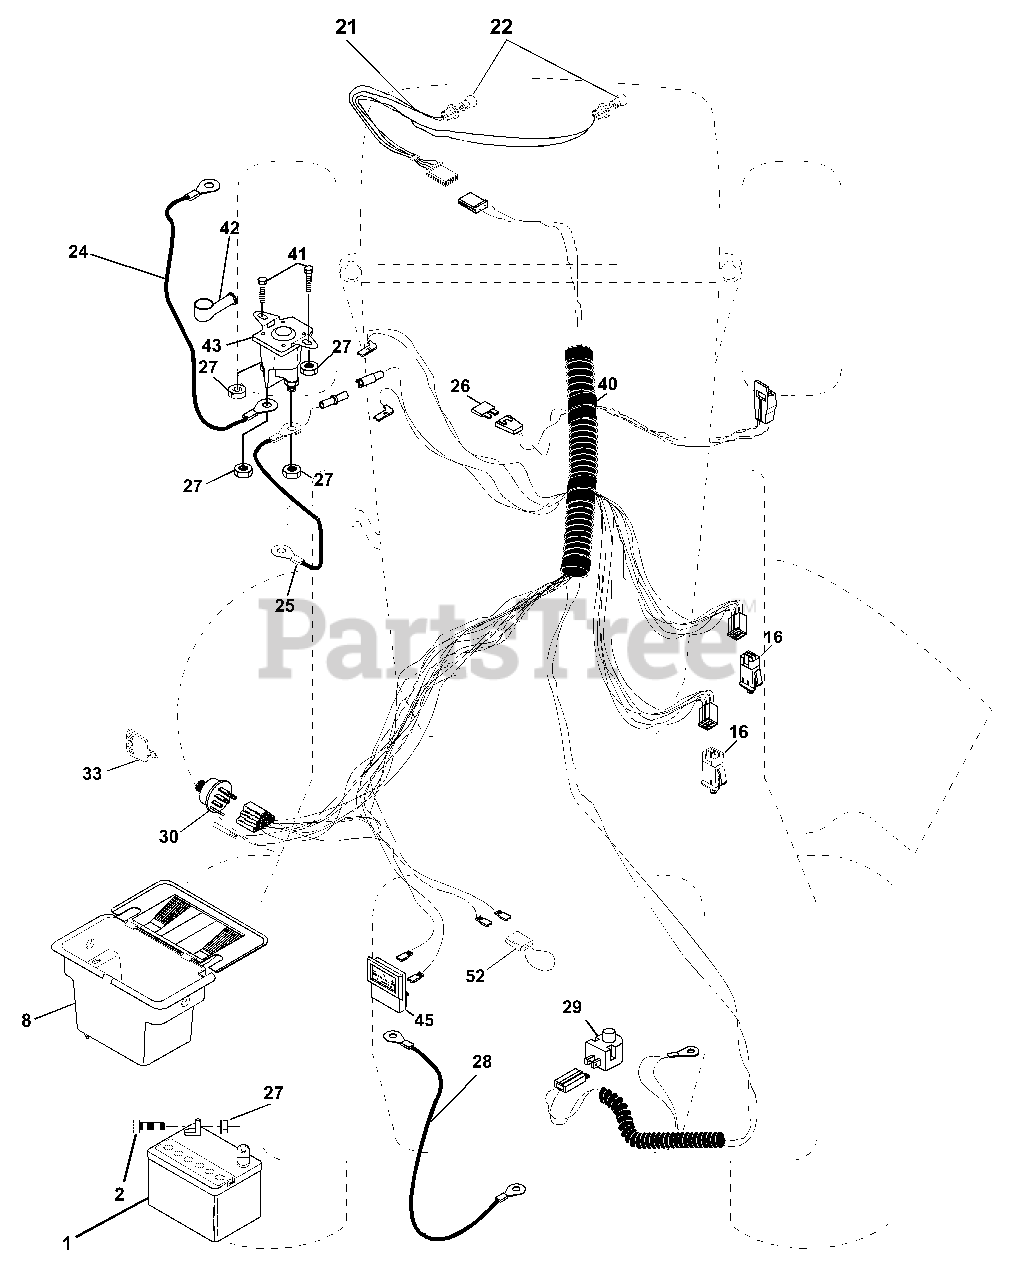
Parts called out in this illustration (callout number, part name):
1	Battery 12 Volt 25 Amp
2	Bolt Hex Hd 1/4-20unc X 3/4
8	Case Battery
16	Switch Interlock Push -In
21	Harness Asm Light W/4152J
22	Bulb Light #1156
24	Cable Battery 6 Ga 11" red
25	Cable Battery 6 Ga w/16 wire, red
26	Fuse 20 AMP
27	Nut Keps Hex 1/4-20 unc
28	Cable Ground 6 Ga 12" black
29	Switch Plunger Nc Gray
30	Switch Ign
33	Key Ign
40	Harness Ign
41	Bolt Blk Fin Hex 1/4-20 X 1/2
42	Cover Terminal Red
45	Ammeter
52	Protection Wire Loop
